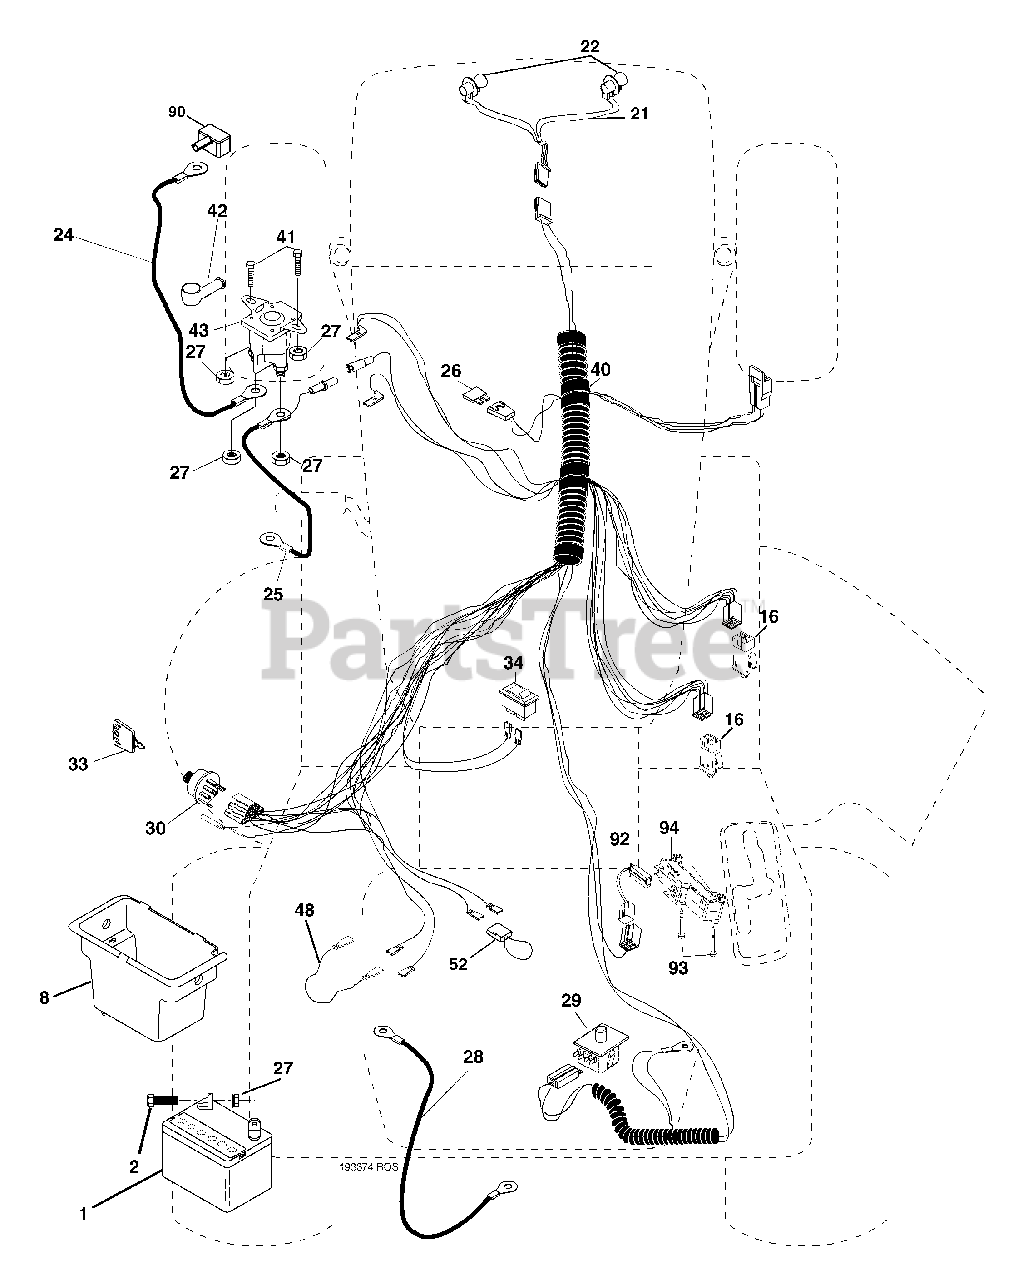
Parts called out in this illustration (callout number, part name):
1	Battery
2	Bolt Hex Hd 1/4-20 unc x 3/4
8	Box Battery
16	Switch Interlock
21	Harness Asm Light W/4152j
22	Bulb Light #1156
24	Cable Battery 6 Ga. 11"red
25	Cable Battery
26	Fuse 20 AMP
27	Nut Keps Hex 1/4-20 unc
28	Cable Ground 6 Ga. 12" Black
29	Switch Seat
30	Switch Ign
33	Key Ign
34	Switch Light/Reset
40	Harness Ign
41	Bolt Blk Fin Hex 1/4-20
42	Cover Terminal Red
43	Solenoid
48	Adapter Ammeter
52	Protection Wire Loop
90	Cover Terminal Battery
92	Harness Pigtail Reverse Switch
93	Screw Plastite 10-14 x 2.0
94	Module Reverse ROS
